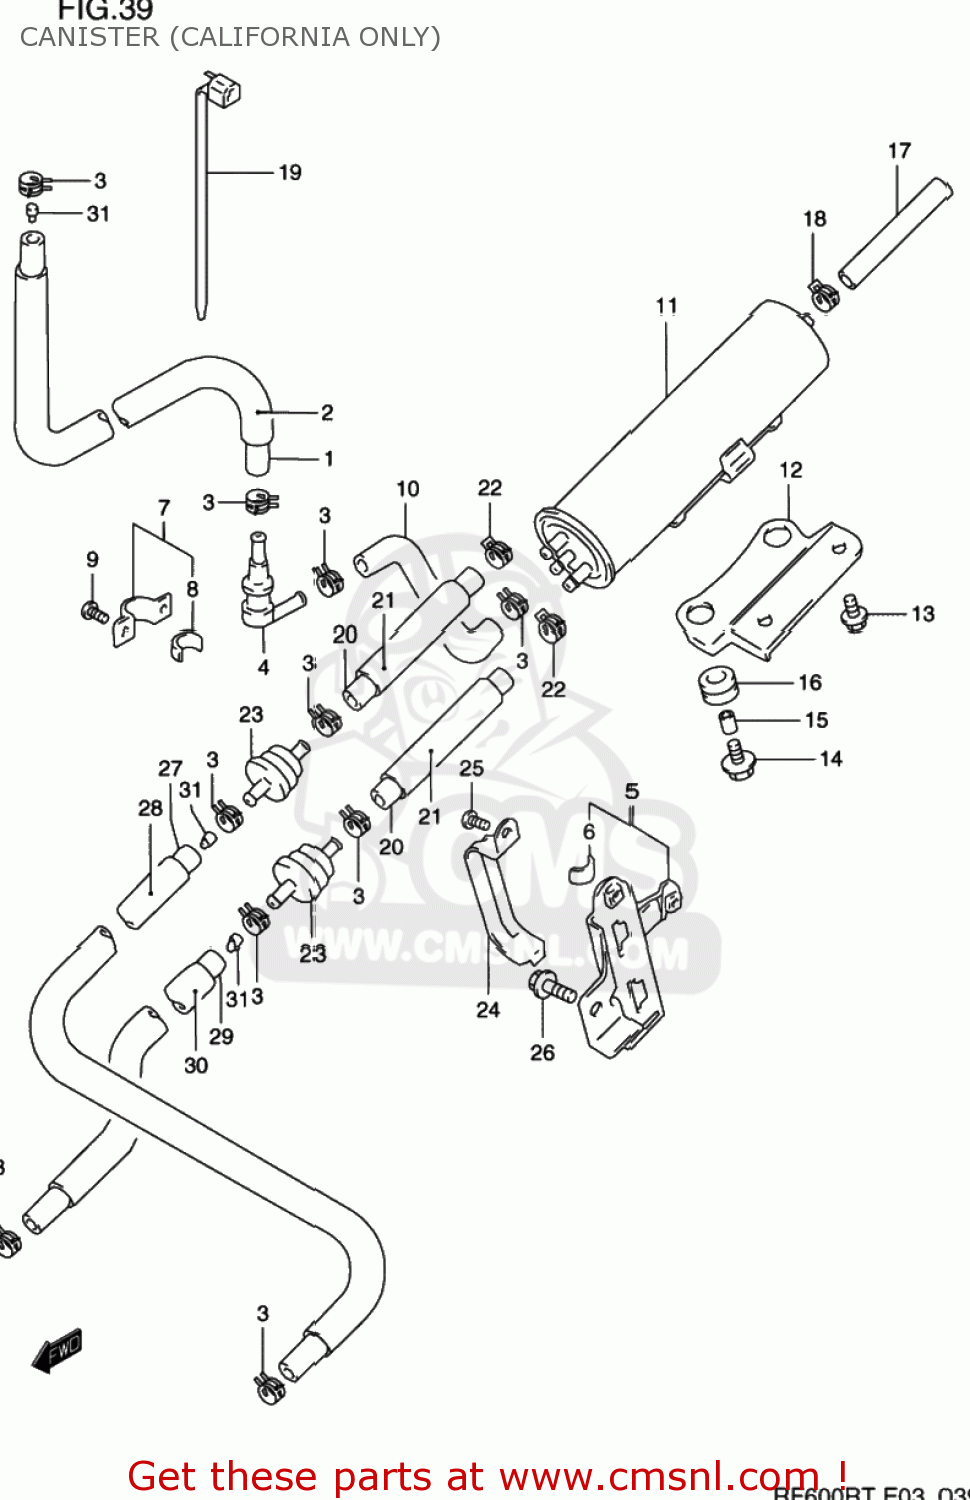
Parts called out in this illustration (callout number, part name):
1	HOSE
2	PROTECTOR(14.5X15.5X600)
3	CLIP
4	VALVE,FUEL TANK BREATHER
5	BRACKET,FUEL TANK BREATHER
6	CUSHION
7	PLATE,FUEL TANK BREATHER NO.2
8	CUSHION
9	SCREW
10	HOSE (5.4X11.4X600)
11	CANISTER ASSEMBLY,CHARCOAL
12	BRACKET,CANISTER
13	BOLT
14	BOLT
15	SPACER
16	CUSHION
17	HOSE (7X12X600)
18	CLIP
19	CLAMP L:165
20	HOSE(5.4X11.4X600)
21	PROTECTOR,EVAPORATOR HOSE,N
22	CLIP
23	VALVE,CANISTER PURGE
24	HOLDER,CANISTER PURGE
25	SCREW
26	BOLT
27	HOSE
28	HOSE
29	HOSE (5.4X11.4X600)
30	PROTECTOR(14.5X15.5X600)
31	JET,MAIN,100
